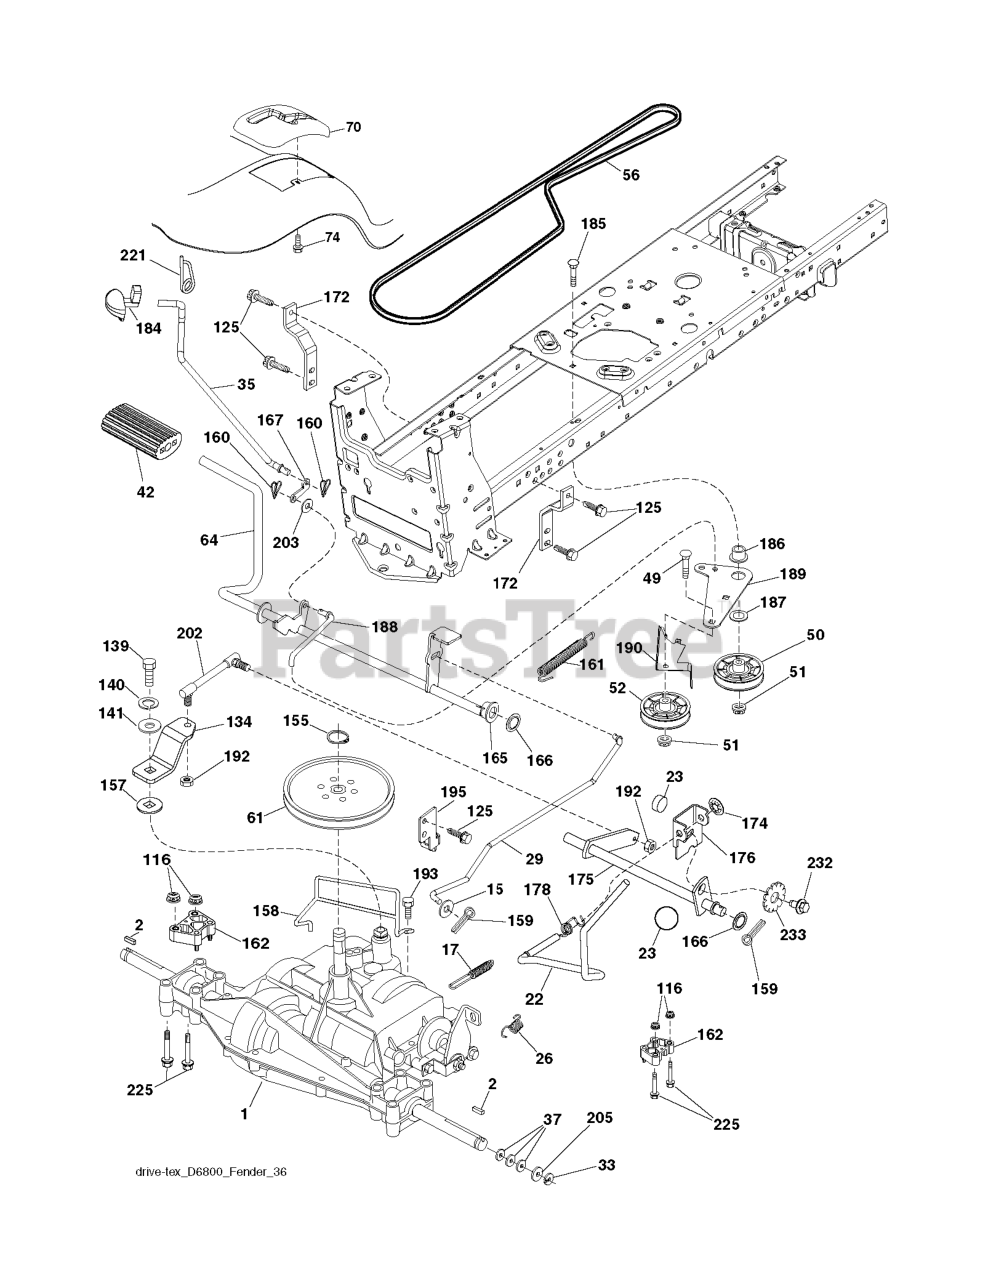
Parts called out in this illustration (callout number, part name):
2	SQUARE KEY
15	WASHER
17	SPRING.BRAKE.PEERLESS.TEX
22	ROD.SHIFT.FENDER.TLT.2006
23	KNOB.DUCKHEAD.1/2
26	SPRING.BRAKE.RTN.GR.DR
29	ROD.BRAKE.PEERLESS
35	ROD.CNTRL.PARK.PREDATOR.LT.TEX
42	PEDAL COVER T
50	IDLER.FLAT.910.OFFSET
51	NUT LOCK FLG 3/8-16 UNC
52	IDLER.V-GROOVE.910.OFFSET
56	V-BELT.TRACTOR.DRIVE.P
61	PULLEY TRANS
64	SHAFT.ASM.PEDAL.BRAKE.
70	CONSOLE.SHIFT.STL.6SP.GREY
74	SCREW.HI-LO.CONSOLE
116	NUT LOCK HEX FLANGE 5/16-18
125	SCREW
134	ARM.SHIFT.
139	BOLT 1/4-28X3/4
140	LOCKWASHER
155	RETAINING RING LT
157	WASH-SHFT PLT LT
158	KEEPER.PMS.18/20.D4365
159	COTTER PIN
160	RETAINER CLIP
161	SPRING.RETURN.CLUTCH.2006
162	SPACER.TRANSAXLE.18&22
165	BUSHING.SHAFT.BRAKE.HAND
166	NUT.PUSH.625.2006
167	LATCH.BRAKE.SPRING
172	STRAP.TRQ.LH.GEAR.DRIV
174	NUT.PUSH.500.2006
175	SHAFT.ASM.SHIFT.
176	ARM.CLEVIS.ROD.SHIFT
178	SPRING.SHIFT.GT2006
184	HANDLE PARKING BRAKE
186	SPACER.RETAINER
187	WASHER 12/32X2X10GA
188	RP.LINK.CLUTCH.GROUND.DRIVE
189	BELLCRANK.GROUND.DRIVE.TEX.
190	KEEPER.BELLCRANK.DRIVE
192	NUT LOCK CENTER 1/4 -28 FNTHD
193	SCREW 5/16"
195	BRKT.ROD.BRAKE.PEERLES
202	LINK.TRANSAXLE.D6800.18/20"TEX
203	WASHER
221	RETAINER.SPRING.CLIP.H
225	BOLT.HEX.FLNG.5/16-18X3.75
226	SCREW.7/16-14X7/8.FLAN
232	BOLT FIN HEX 7/16-14 X 1
233	WASHER SERRATED
